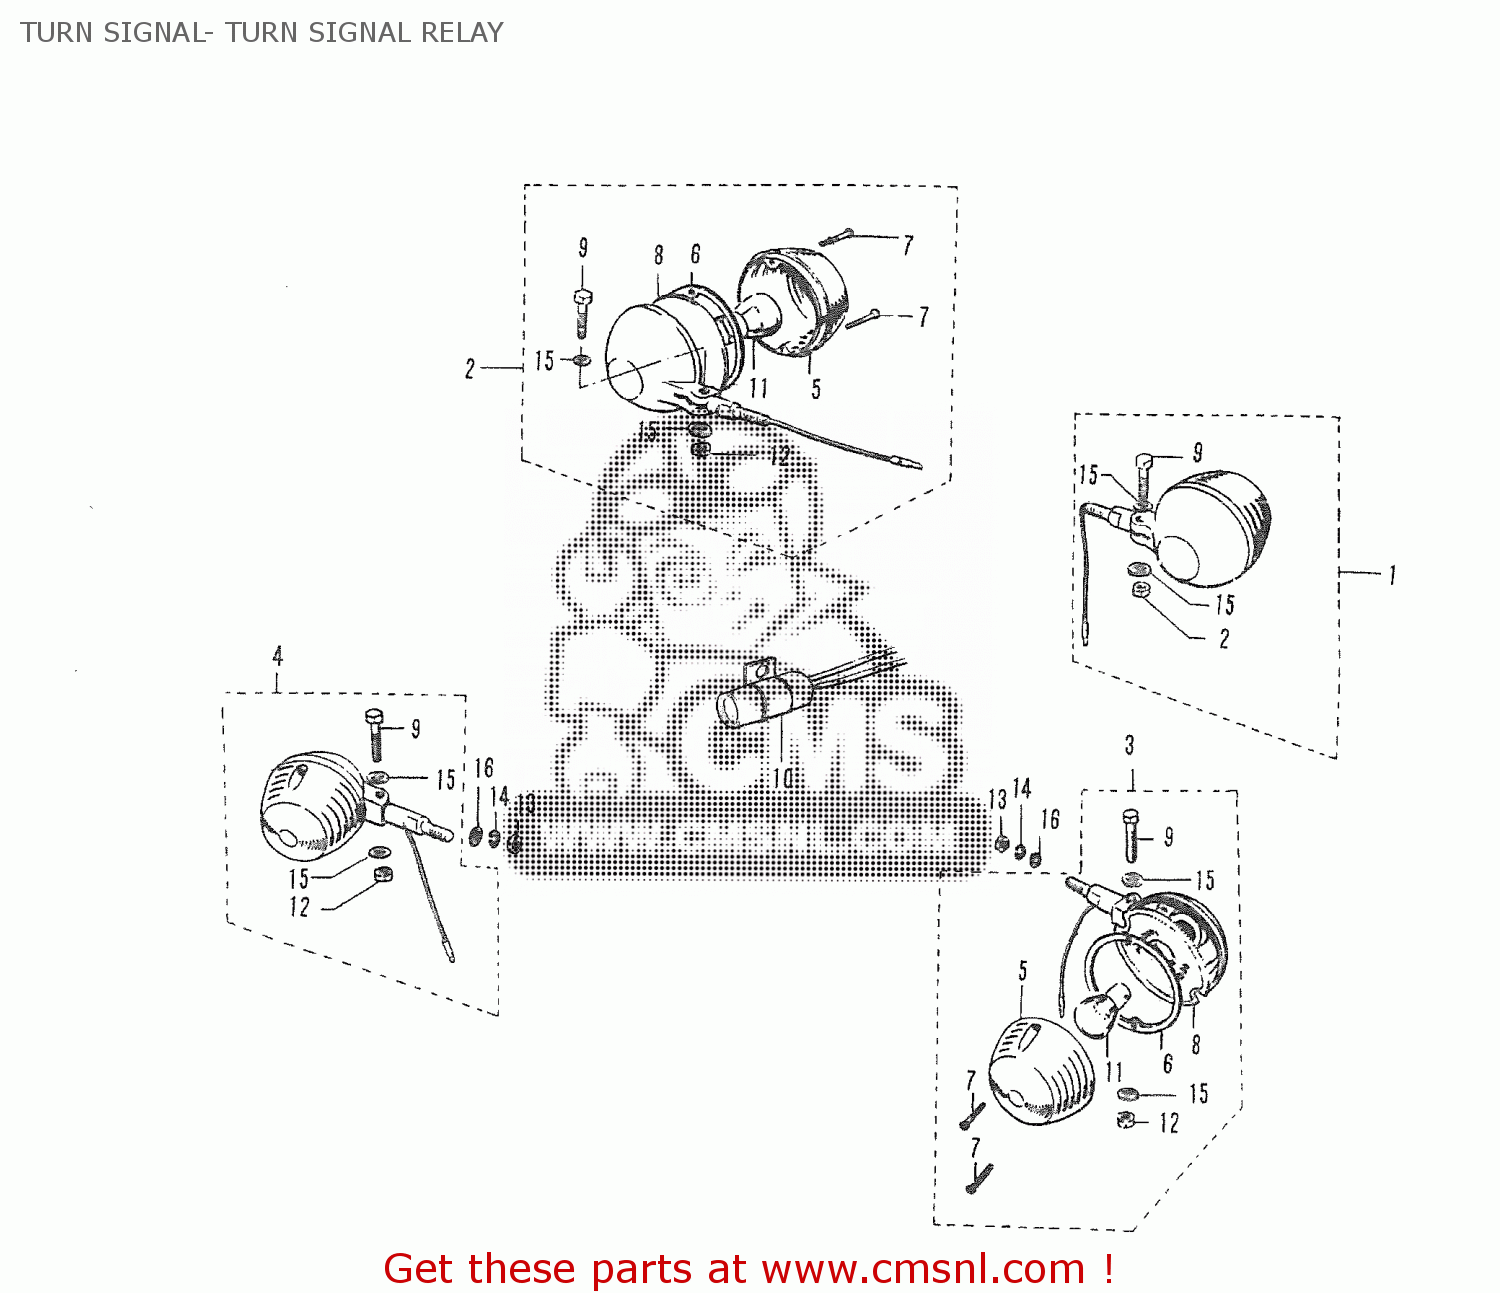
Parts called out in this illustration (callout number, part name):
1	LAMP ASSEMBLY,FRONT TURN SIGNAL
2	LAMP ASSEMBLY,FRONT TURN SIGNAL
3	LAMP ASSEMBLY,REAR TURN SIGNAL
4	LAMP ASSEMBLY,REAR TURN SIGNAL
5	LENS,TURNSIGNAL
6	GASKET,TURNSIGNAL LENS (NAS)
7	TURN SIGNAL LENS FITTING SCREW
8	REFLECTOR
9	BOLT,HOUSING
10	RELAY,TURN SIGNAL
11	BULB(12V23W,STANLEY,A4577A)
12	HEXAGON NUT
13	SMALL HEXAGON NUT
14	LOCK WASHER
15	SMALL FLAT WASHER
16	WASHER
